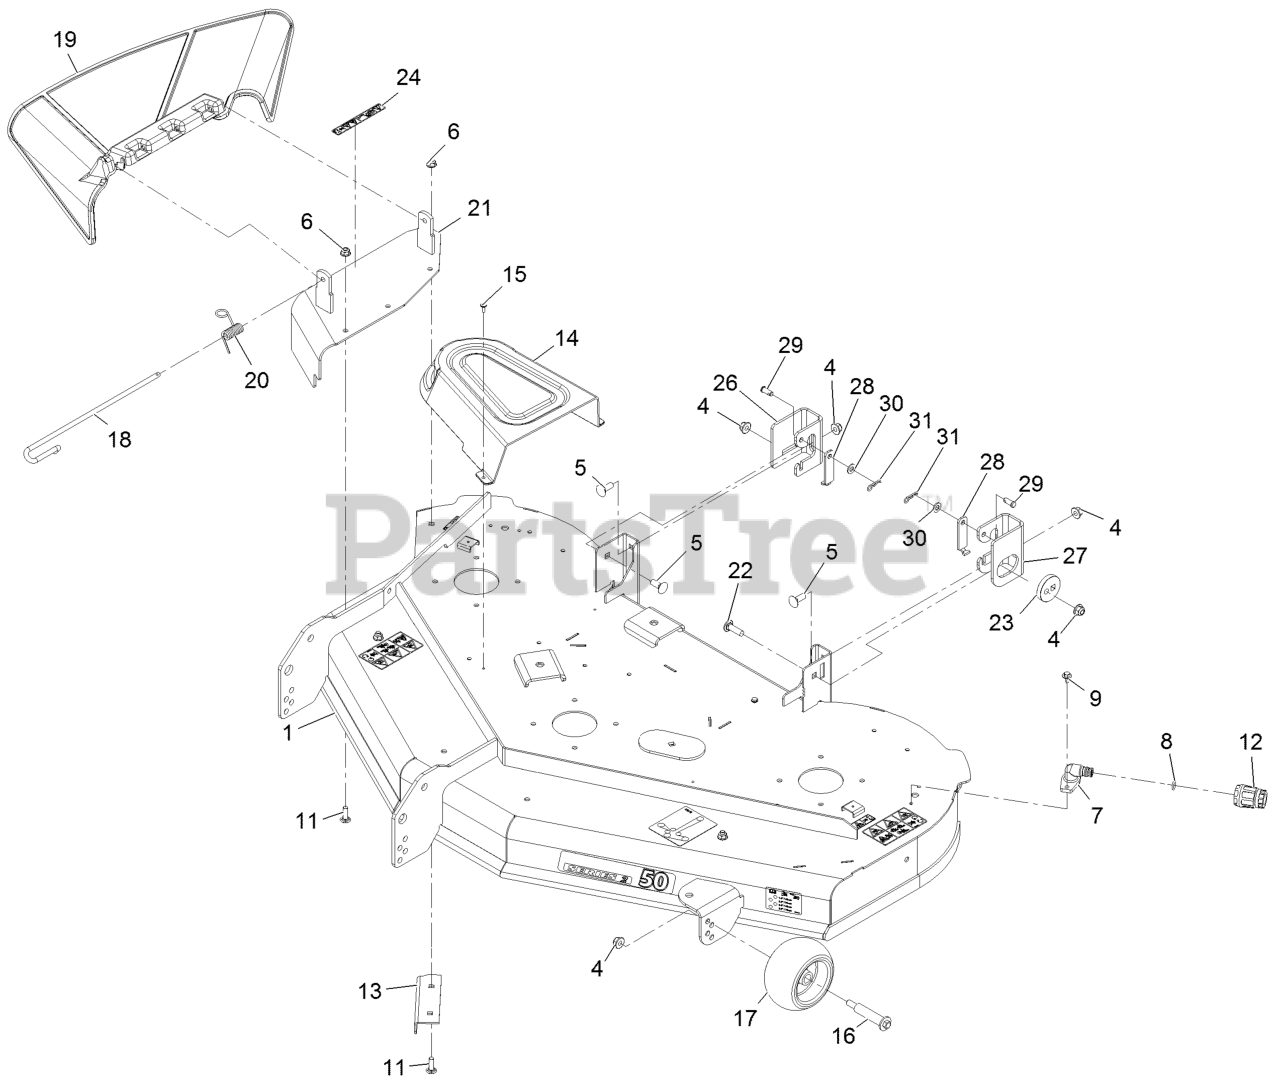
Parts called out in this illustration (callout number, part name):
1	50" DECK AND DECAL ASM (E
4	NUT-HF, NI
5	BOLT-CARR
6	NUT-HF, NI
9	SCREW-HHFTF
11	SCREW-CARR
12	CONNECTOR-HOSE
13	BAFFLE-CUTOFF
14	COVER-BELT
15	SCREW-TAPTITE
16	BOLT-SHOULDER
17	ROLLER-SCALP, ANTI
18	PIN-CHUTE
19	DEFLECTOR-DISCHARGE
20	SPRING-TORSION
21	COVER-DISCHARGE
22	Bolt-Carriage 3/8-16 X 1 1/4
23	ECCENTRIC
24	DECAL-DANGER
26	BRACKET - HANGER, RR
27	BRACKET - HANGER, LR
28	LINK - DECK RETENTION
29	PIN-CLEVIS
30	WASHER-PLAIN
31	PIN-COTTER
